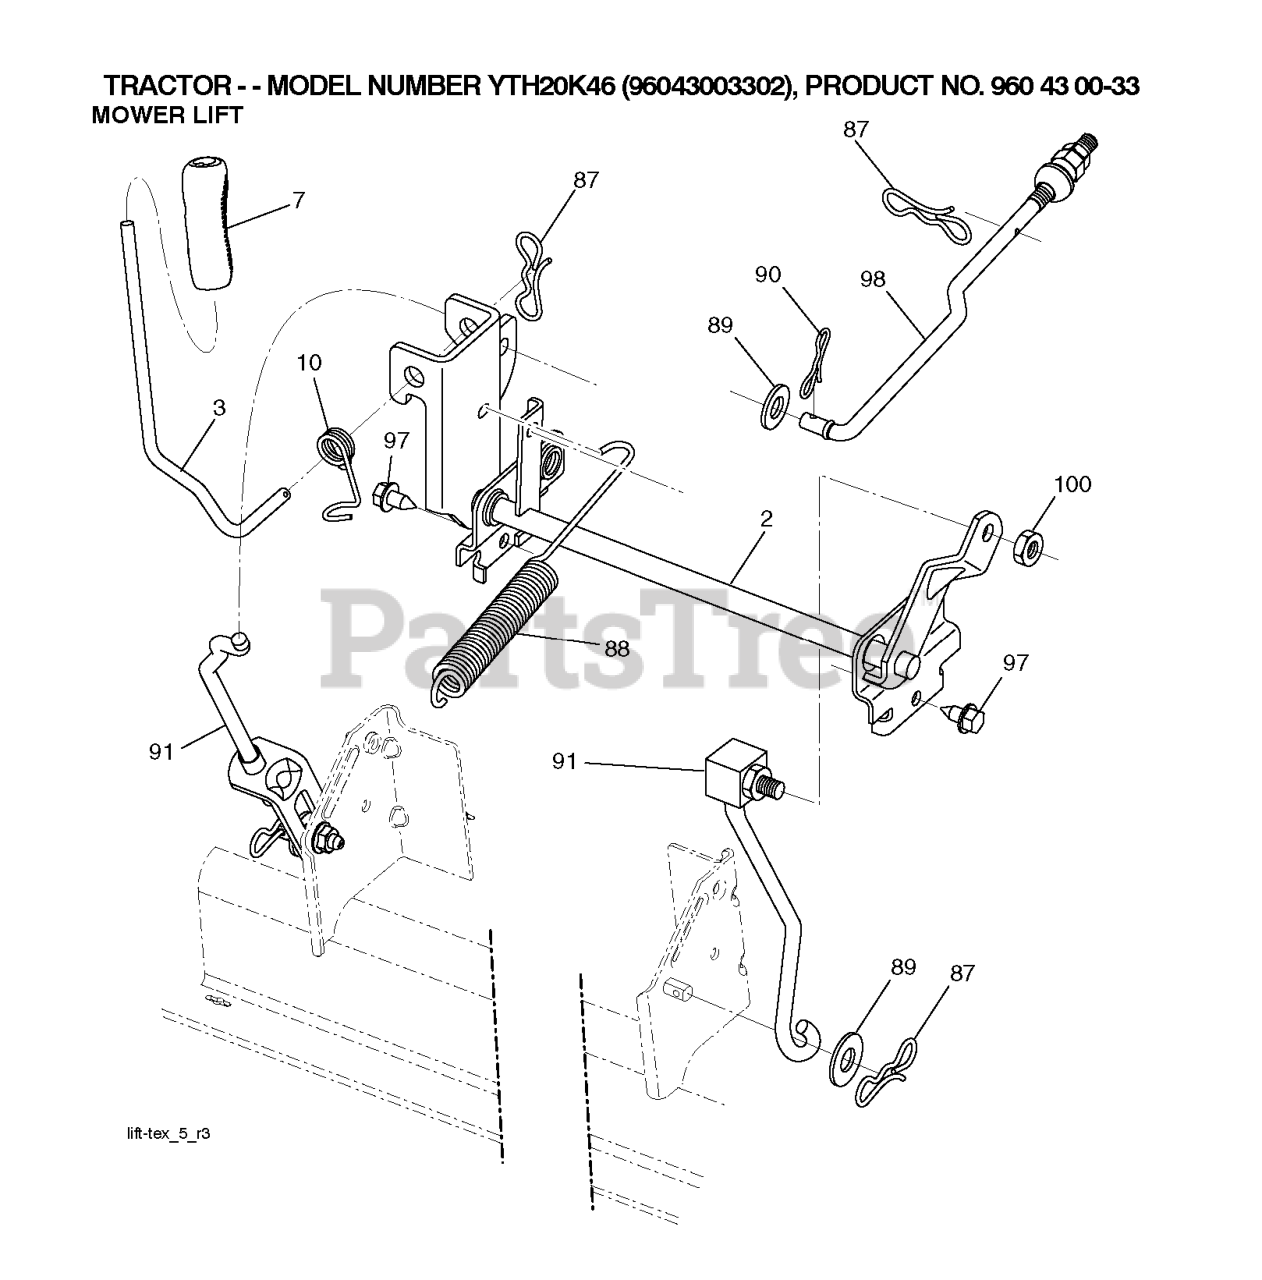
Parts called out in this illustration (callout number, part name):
2	SHAFT.ASM.LIFT.CROSS.H
3	LEVER.LIFT.HANDLE.LT
7	GRIP.HANDLE.LIFT.PVC.BLACK
10	SPRING.TORSION.LIFT.HANDLE
87	PIN.COTTER.7/16.BOW TI.
88	SPRING.LIFT.ASSIST
89	WASHER.CLEAR.ZINC
90	PIN.COTTER.5/16.BOW TI
91	LINK.ASM.LIFT.REAR
97	SCREW, 3/8-16X3/4
98	LINK.ASM.SUSP.FRONT.MW
100	LOCKNUT
